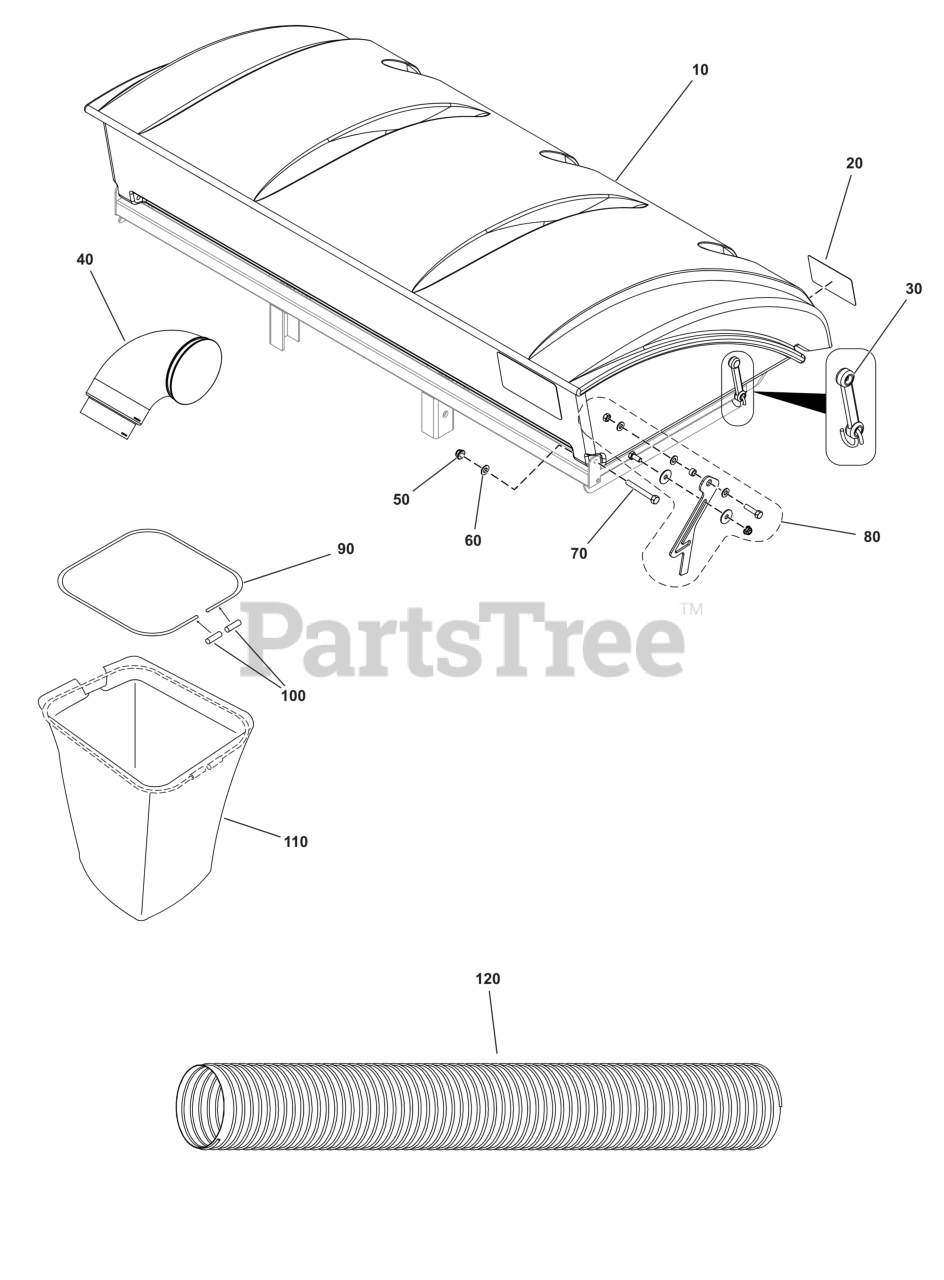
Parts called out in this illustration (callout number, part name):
10	TOP ASSEMBLY / P3B / FERRIS - NET
20	RED REFLECTOR DECAL - NET
30	RUBBER STRAP W/HOOKS - NET
40	INLET
60	WASHER, 1/2" SAE
70	BOLT, 1/2-13 X 2-1/2
80	VAC KIT HW / P3B / FERRIS - NET
90	PART B0227 BAG RING / GENERIC - NET
100	PART J0274 VINYL CAP - NET
120	CONNECTOR-TUBE
